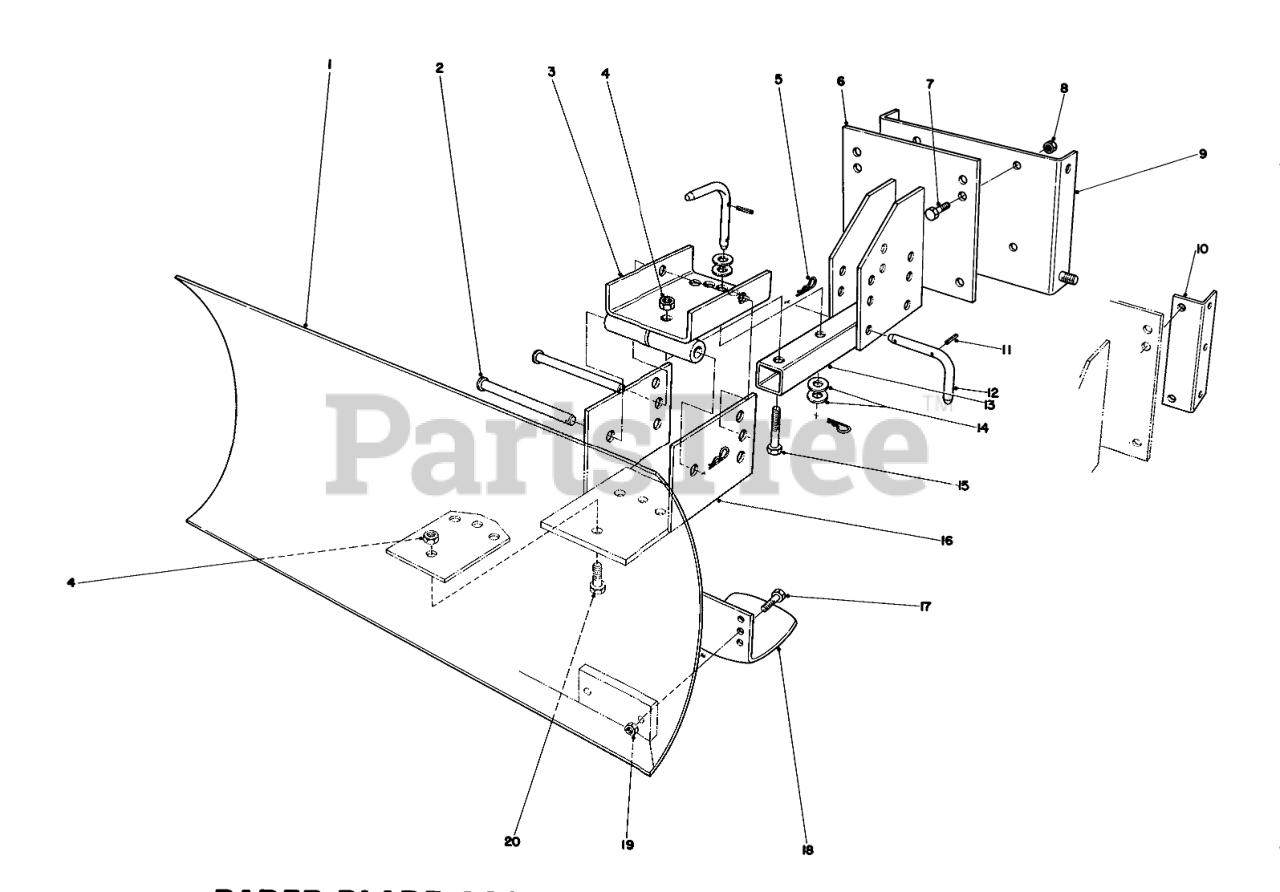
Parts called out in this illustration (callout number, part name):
1	Blade
2	PIN-CLEVIS
3	Swivel Bracket
4	1/2-13 CONELOCK NUT
5	PIN-HAIR
6	Mounting Plate
7	SCREW-HH
8	NUT-LOCK, CONE
9	Mounting Plate (Used with 826 & 1132 Units only)
10	Mounting Rail (used with 421 units only)
11	PIN-SPRING
12	Pivot Pin (Incl. Ref. #11)
13	Blade Tongue
14	WASHER-FLAT
15	SCREW-HH
16	Blade Adjustment
17	SCREW-HH
19	NUT-LOCK, CONE
20	SCREW-HH
